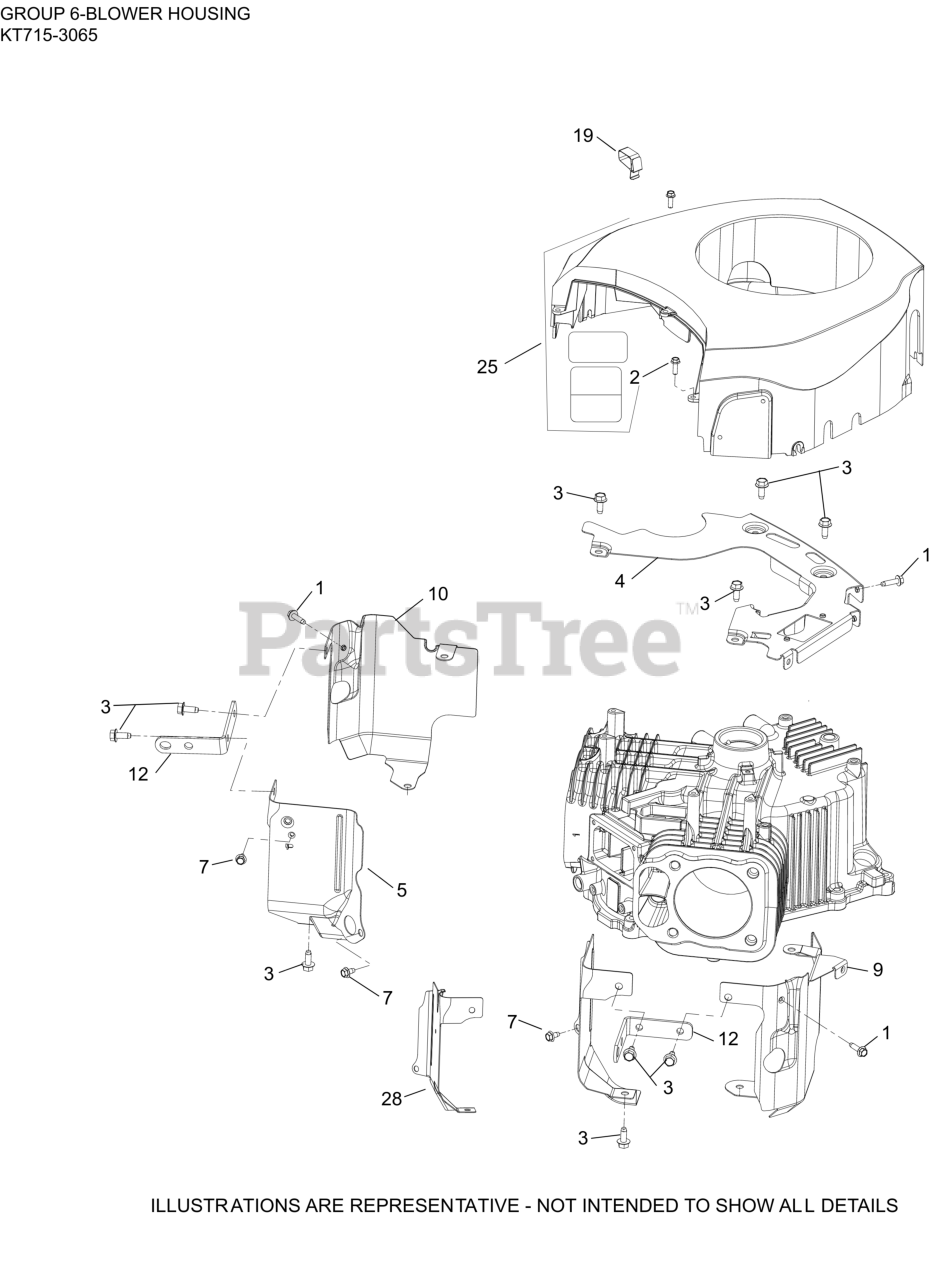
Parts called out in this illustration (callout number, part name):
1	SCREW, THD FRM-USE 25 086 473-S
2	SCREW, HI-LOW
3	SCREW, THREAD FORMING
4	PLATE, BACKING
5	BAFFLE, VALLEY #1
7	SCREW, THREAD FORMING
9	BAFFLE, LEFT BARREL
10	BAFFLE, RIGHT BARREL
12	STRAP, LIFTING
19	CLIP, BLOWER HOUSING
25	KIT, BLOWER HOUSING
28	BAFFLE, VALLEY #2
